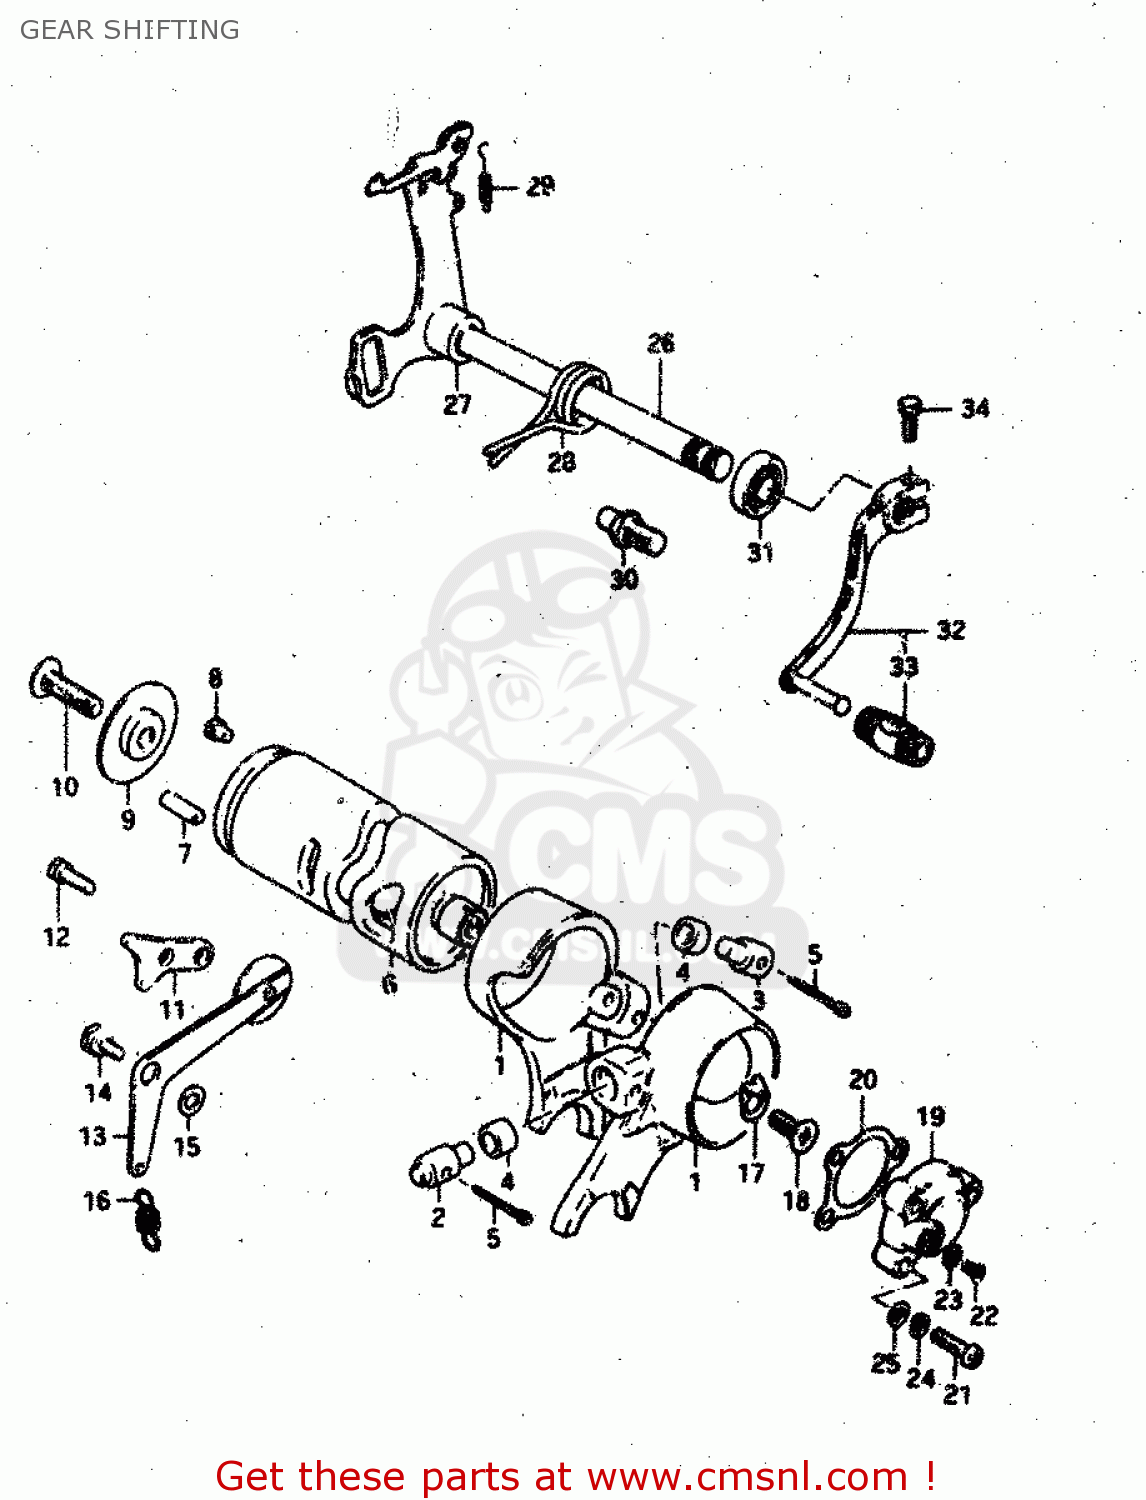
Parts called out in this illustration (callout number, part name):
1	FORK,GEAR SHIFT
2	PIN
3	PIN
4	SPACER(6X9.8X6)
5	PIN 25X20
6	CAM
7	ROLLER(4X13.8)
8	PIN (2)
9	RETAINER,GEAR SHIFT CAM
10	SCREW
11	GUIDE, CAM
12	BOLT, UPPER
13	STOPPER,GEAR SHIFT CAM
14	BOLT(6X16.1)
15	WASHER
16	SPRING
17	CONTACT,GEAR SHIFT SWITCH
18	SCREW
19	SWITCH,NEUTRAL INDICATOR
20	GASKET,GEAR SHIFT SWITCH (NAS)
21	SCREW
22	SCREW
23	WASHER
24	LOCK WASHER
25	WASHER
26	SHAFT,GEAR SHIFT
27	SPACER(12X20X15.3)
28	SPRING
29	SPRING
30	STOPPER,GEAR SHIFT ARM
31	OIL SEAL
32	LEVER ASSY,GEAR SHIFT
33	RUBBER,GEAR SHIFT PEDAL
34	BOLT
